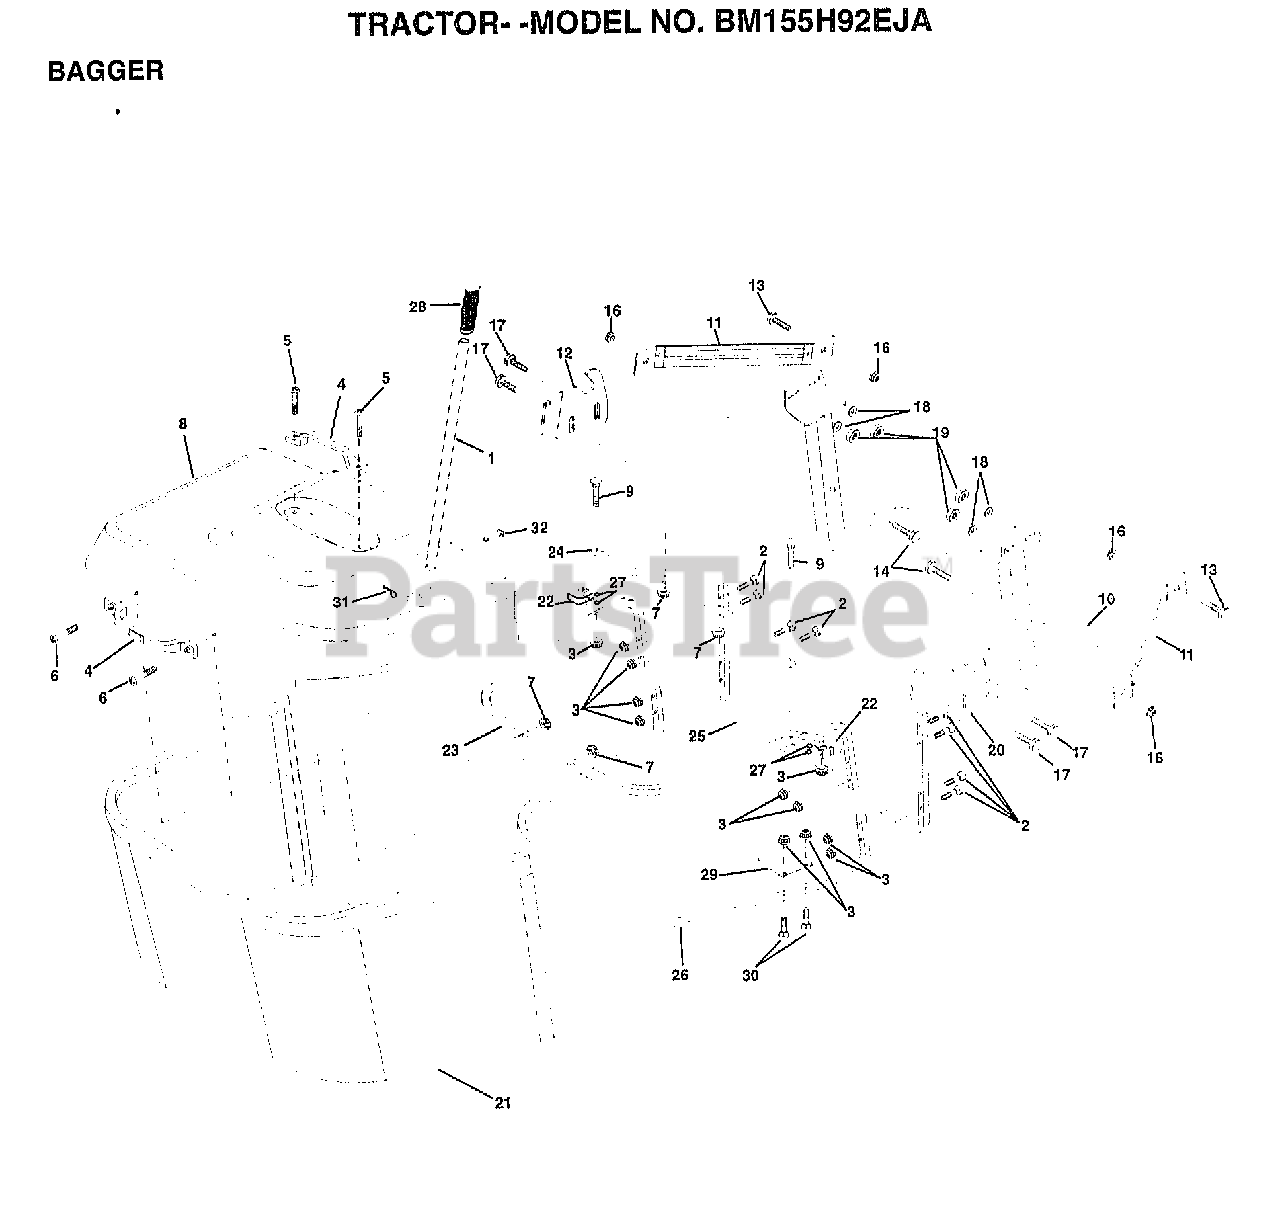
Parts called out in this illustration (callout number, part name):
1	TUBE.HDLE.BAG.CRD
2	BOLT.CARRIAGE.1/4-20X2.0
4	HANDLE.GRAB.BLACK.
5	"SCREW,PAN.HEAD"
8	COVER.BAG.PLASTIC.CRD
9	BOLT CARRIAGE
10	SUPT.ASM.WLDMNT.BAG.CRD
11	BRKT.SUPT.UPPER.BAG.CRD
12	BRKT.PIVOT.BAG.LH.CRD
13	BOLT
14	BOLT.HEX.3/8-16X2-1/2
17	BOLT
18	WASHER
19	NUT
20	"BRKT.PIVOT.BAG,RH.CRD"
21	BAG.ASM.CRD
22	BRKT.SIDE.BAG.CRD
23	TUBE.UPPER.BAG.CRD
24	TUBE.PIVOT.BAG.CRD
25	TUBE.FT.BAG.CRD
26	TUBE.LOWER.BAG.CRD.
27	GROMMET.EXTRUDED
28	GRIP.HANDLE.BLACK
29	PLATE.STOP.BAG.HDLE.CRD
30	BOLT.CARRIAGE
31	RETAINER M
32	RIVET.DRILL.1.75
